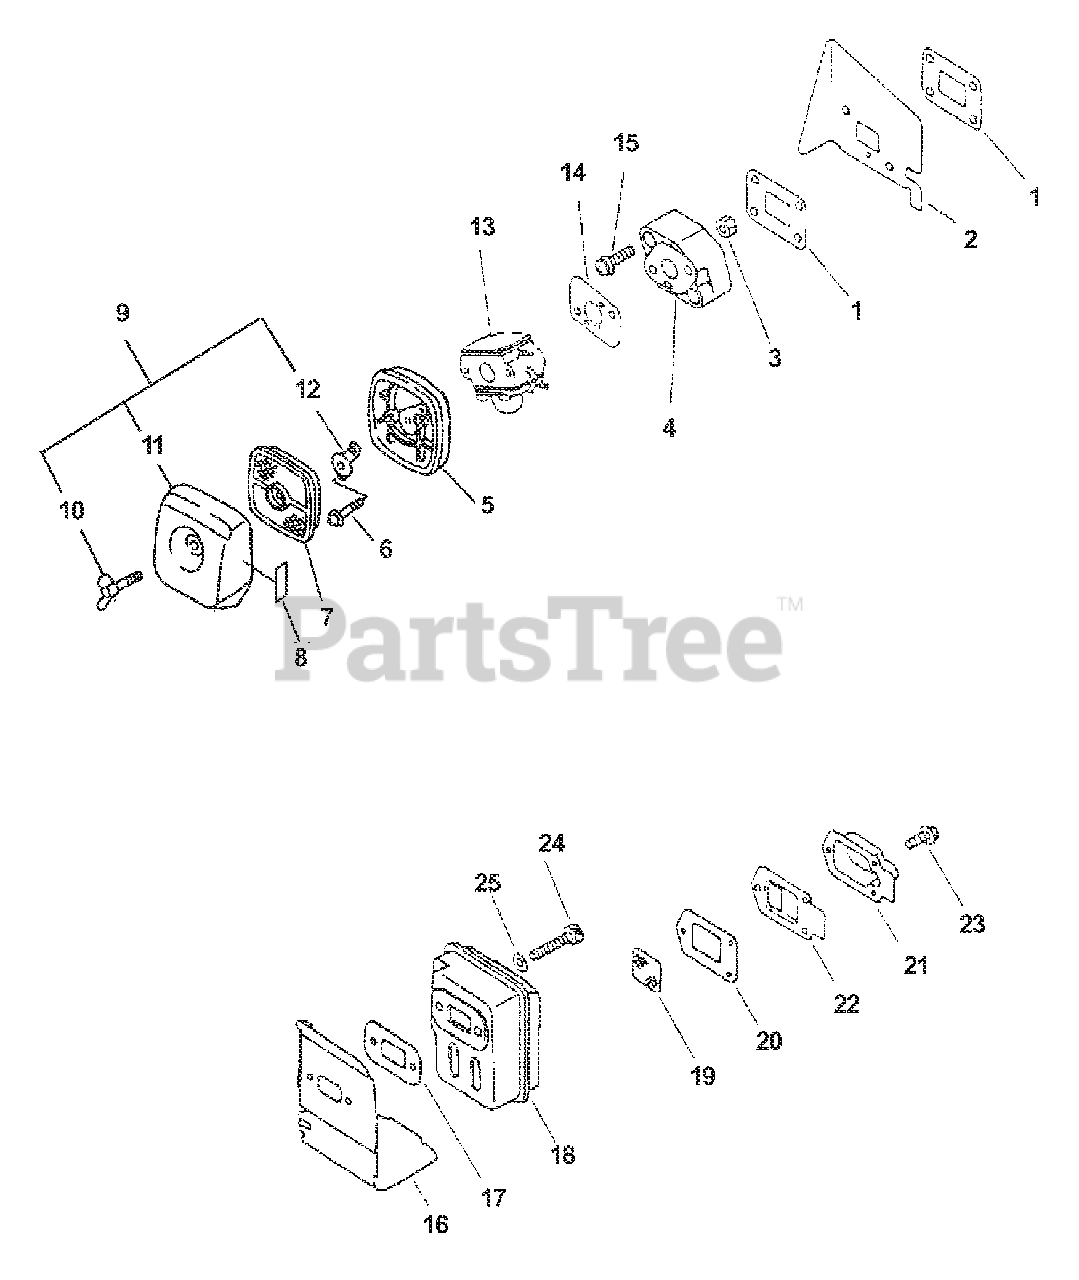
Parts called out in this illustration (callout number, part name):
1	GASKET, INTAKE
2	HEAT SHIELD, INTAKE
3	NUT M5
4	INSULATOR, INTAKE
5	AIR FILTER CASE ASSY
6	SCREW 5×65
7	FILTER, AIR - SINGLE LAYER
8	LABEL, CHOKE
9	COVER, AIR FILTER
10	BOLT, WING 5×20
11	COVER, AIR FILTER - GRAY
12	PLATE, PREVENT
13	CARBURETOR - C1U-K43
14	GASKET, INTAKE
15	SCREW 5×22
16	COVER, MUFFLER
17	GASKET, EXHAUST
19	SCREEN, SPARK ARRESTER
20	GASKET, EXHAUST
21	GUIDE, EXHAUST
21	GUIDE, EXHAUST - INNER
22	GUIDE, EXHAUST
23	SCREW 4×10
24	BOLT 5×55
25	WASHER 5.5×12×0.8
